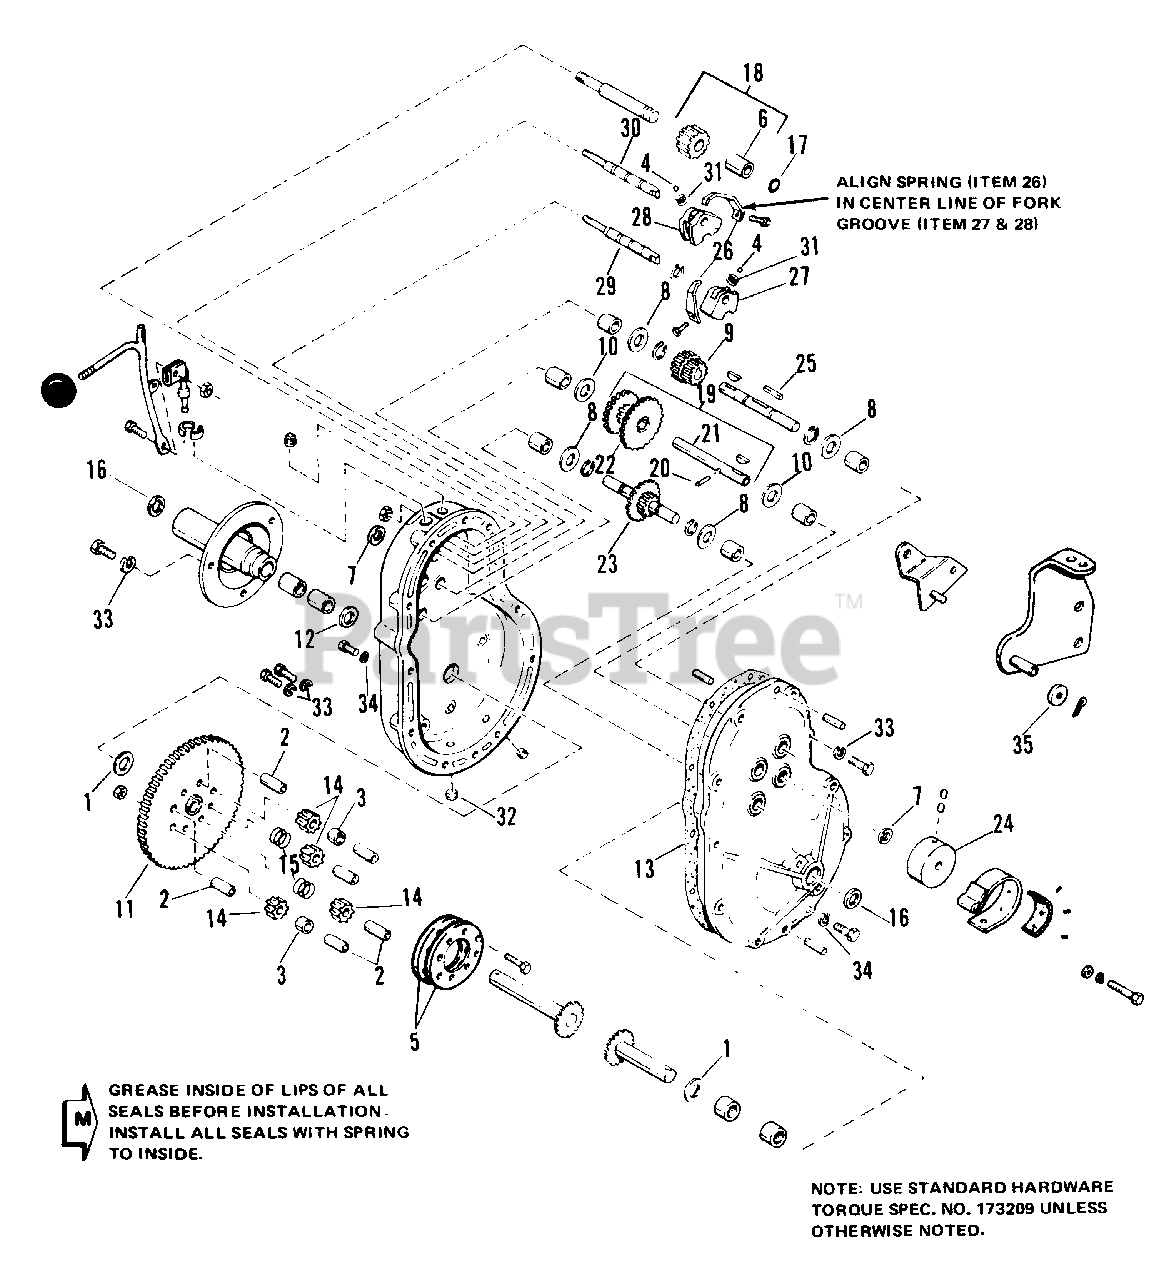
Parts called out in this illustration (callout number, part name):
1	WASHER (6008)(03566)
1	WASHER (6011)
2	SPACER, Pinion Diff.
3	SPACER, Diff.
4	BALL, Shiftlock
5	PLATE, Diff.
6	BEARING, Roller
9	PINION ASSY., Hi & Lo
11	GEAR ASSY., Drive (6008)(03566)
11	GEAR ASSY., Drive (6011)
13	GASKET, Case
14	PINION, Diff.
16	SEAL, Oil (6008)(03566)
16	SEAL, Oil (6011)
18	PINION, Reverse, (Includes Ref. No. 6)
19	SHAFT & GEAR ASSY
20	DOWEL, Pin
21	SHAFT, Brake
22	CLUSTER GEAR ASSY
23	GEAR & SHAFT ASSY
24	DRUM, Brake
27	FORK, Shift Rev.
28	FORK, Shift 1 & 2
29	SHAFT, Shift, Rev & Lo
30	SHAFT, Shift, Hi & Lo
32	PIPE, Plug, Sq. Hd., 3/8
33	LOCKWASHER, Spring, 3/8
34	LOCKWASHER, Spring, 5/16
35	WASHER, Plain, 1/4
